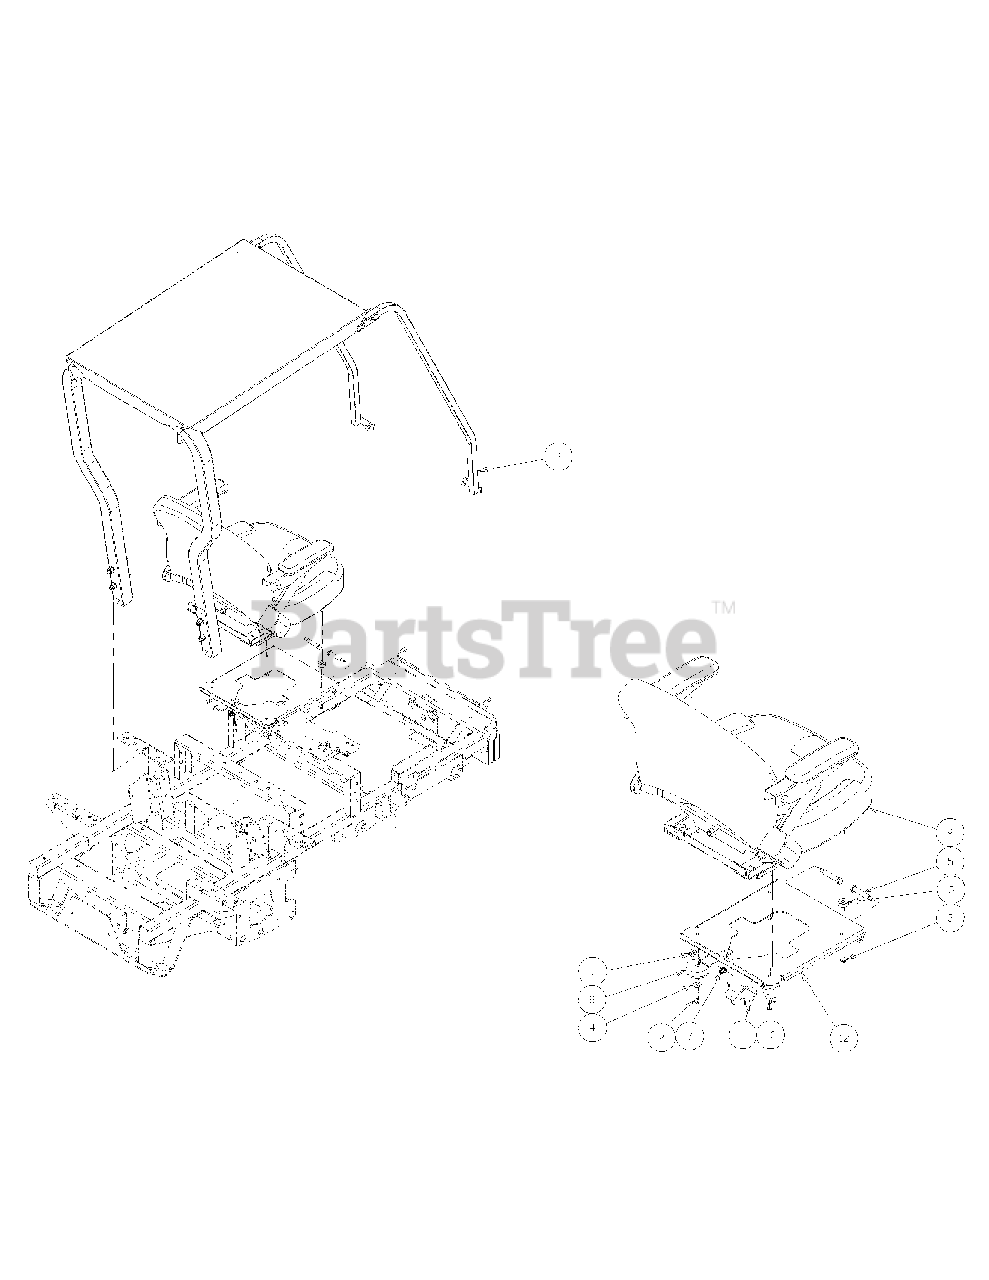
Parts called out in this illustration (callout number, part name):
1	Nut, Hex 3/8-16 Flange Lock
2	Lock Nut, Hex Flange, 5/16-18
3	Spacer, .412 x 1.125 x .44
4	Washer
5	Shoulder Screw, .50x2.345, 3/8-16
6	Grommet, 2.5 OD x 1.0 Long
7	Deck Lift Spring, Right Hand
8	Rops Assembly includes:
9	Seat Assembly, w/ Suspension & Seat Belts
10	Shoulder Bolt, 1/2 x 3/4, 3/8-16
11	Seat Latch
12	Seat Bracket
